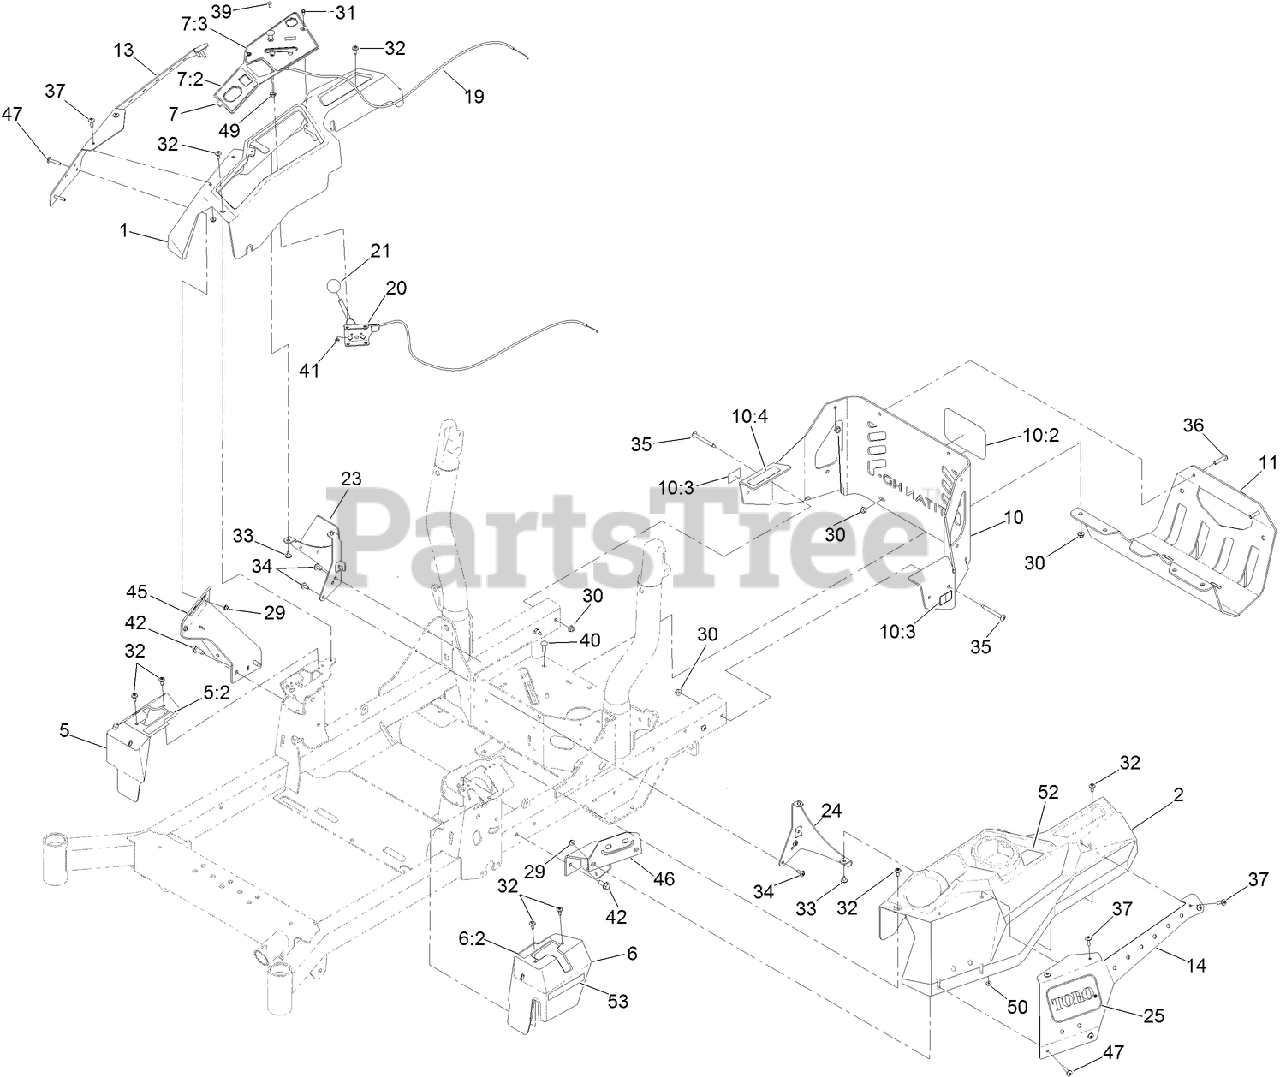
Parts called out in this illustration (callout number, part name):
1	CONSOLE-RH
2	CONSOLE-LH
5	COVER-CONTROL, MOTION (RH)
6	COVER-CONTROL, MOTION (LH)
7	CONTROL PANEL ASM
7:2	DECAL-PANEL, CONTROL
7:3	DECAL-PANEL, CONTROL
10	REAR GUARD ASM
10:2	DECAL
10:3	DECAL-WARNING
10:4	DECAL-ARRESTOR, SPARK
11	GUARD-MUFFLER
13	COVER-POD, RH
14	COVER-LH
19	CABLE-CONTROL, CHOKE
20	CABLE-CONTROL, THROTTLE
21	KNOB-BALL
23	SUPPORT-CONSOLE, RH
24	BRACKET-CONSOLE, LH
25	DECAL
29	NUT-HF
30	NUT-HF, NI
31	SCREW-HWH
32	SCREW-SHOULDER
33	SCREW-TORX
34	SCREW-TORX
35	SCREW-TORX
36	SCREW-TORX
37	SCREW-TRUSS
39	BOLT-CARR
40	SCREW-CARR
41	NUT-LOCK, NI
42	SCREW-FORMING, THREAD
45	BRACKET-SUPPORT, POD (RH)
46	BRACKET-SUPPORT, POD (LH)
47	SCREW-TRUSS
49	NUT-HJ
50	NUT-KEPS
52	DECAL-FILL, FUEL
